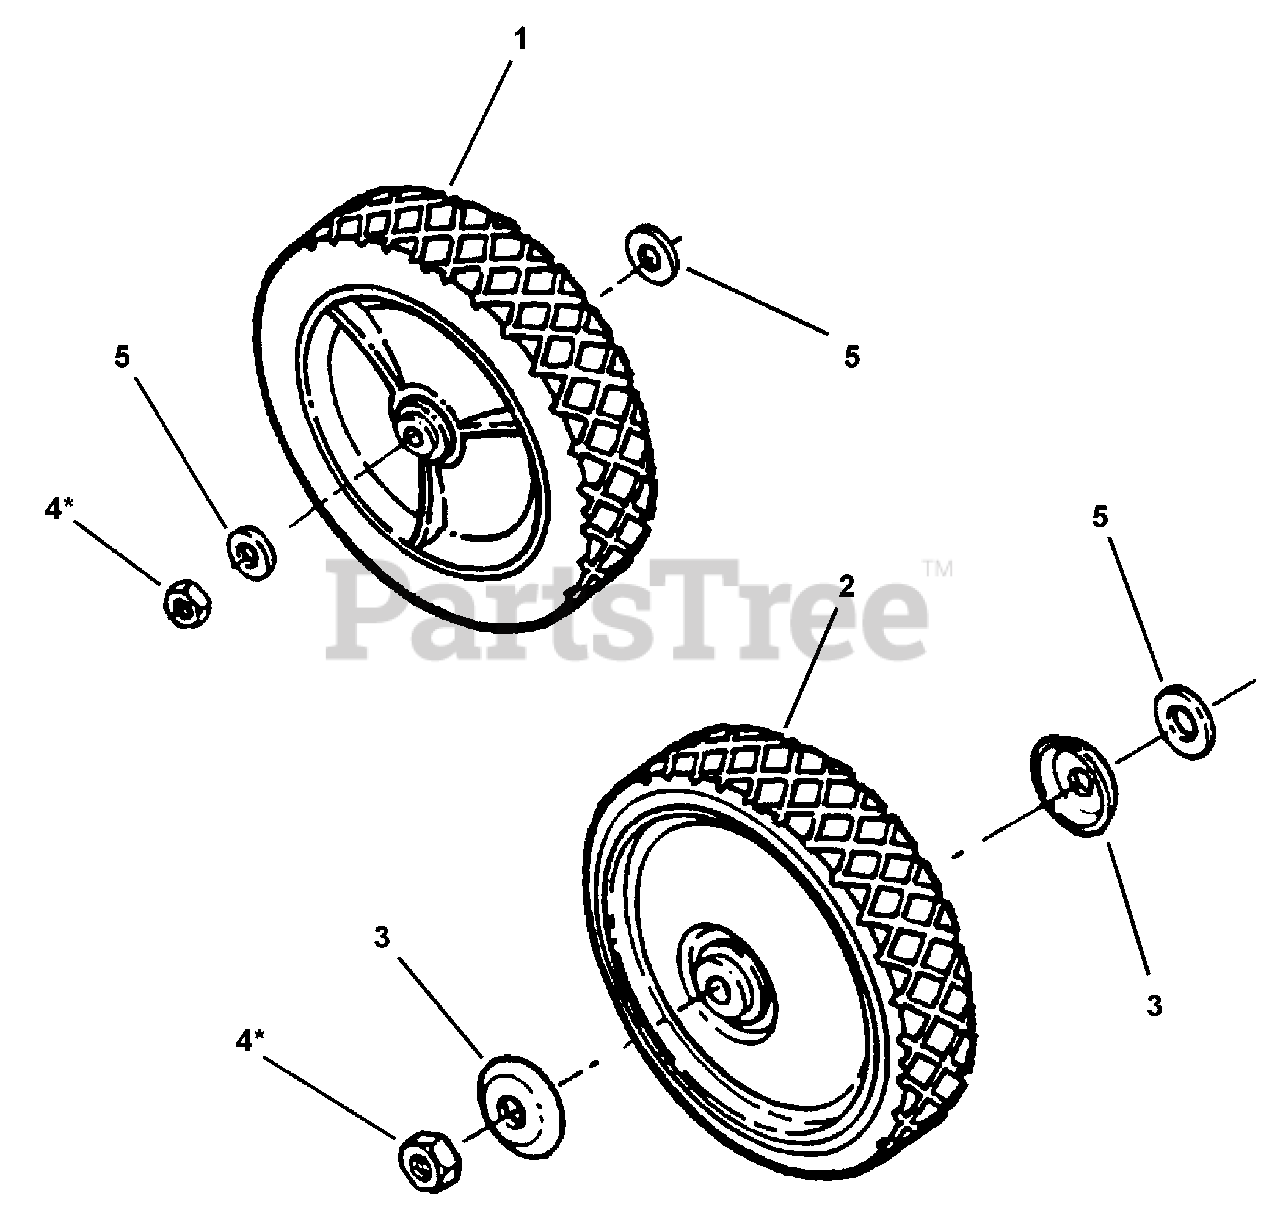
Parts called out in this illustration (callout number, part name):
1	WHEEL, 8 x 1.75 Plastic
2	WHEEL, 8 x 1.75
3	HUB-CAP
4	NUT, 7/16-20 Hex (Thin)
5	WASHER, 7/16 x 1" O.D. Flat
